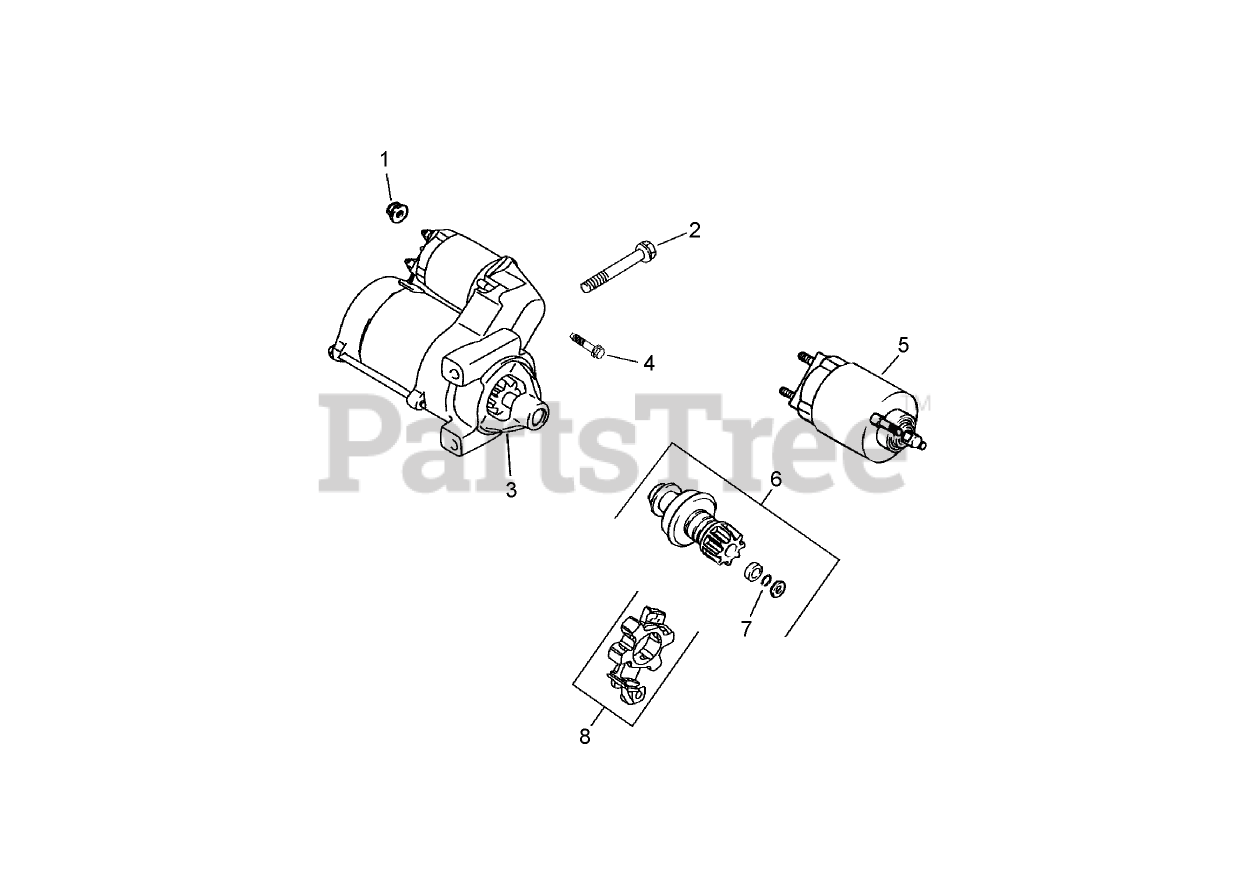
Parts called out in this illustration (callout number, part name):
1	NUT-FLANGE (M8X1.25)
2	SCREW-FLG (M8X1.25X80)
3	Starter ASM (Includes 4-8)
4	SCREW-TORX HEAD, EXTERNAL
5	Solenoid Kit (Includes 4)
6	Pinion Drive Kit (Includes 7)
7	Ring
8	BRUSH HOLDER KIT
